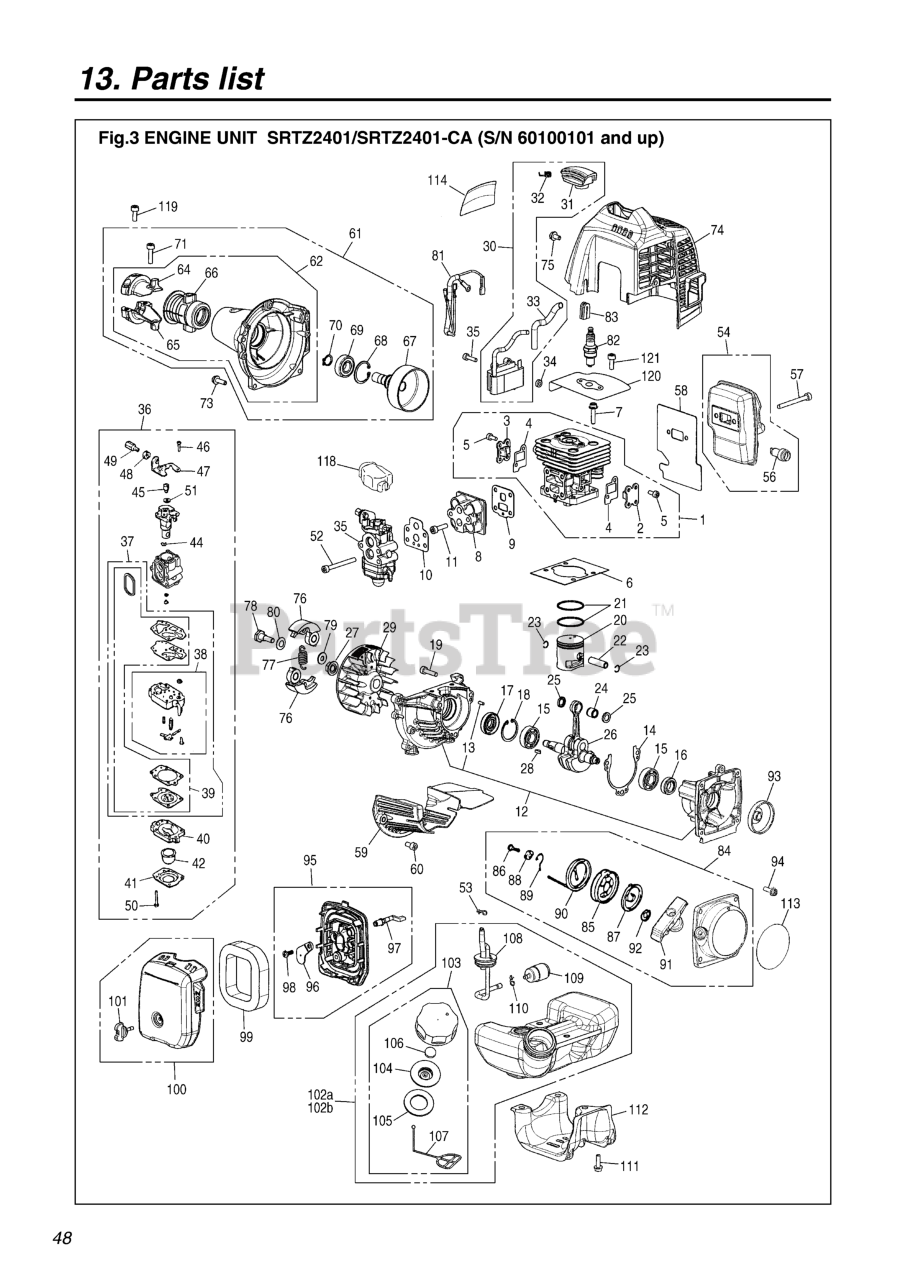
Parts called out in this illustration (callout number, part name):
1	CYLINDER COMP
2	COVER, TR-S
3	COVER, TR-F
4	GASKET, TR
5	BOLT
6	GASKET, BASE
7	BOLT TORX
8	INSULATOR
9	GASKET
10	GASKET
11	BOLT, TORX
12	CRANKCASE COMP
13	PIN
14	GASKET, CASE
15	BEARING
16	SEAL
17	SEAL
18	RING
19	BOLT TORX
20	PISTON
21	RING
22	PIN
23	RING
24	BEARING
25	WASHER
26	CRANKSHAFT COMP
27	NUT
28	KEY
29	ROTOR
30	COIL ASSY
31	CAP
32	SPRING
33	TUBE
34	SPACER
35	BOLT TORX
36	CARBURETOR ASSY
37	REBUILD KIT
38	BODY ASSY
39	GASKET KIT
40	BODY
41	COVER
42	PUMP
44	RING
45	SWIVEL
46	SCREW
48	NUT
49	SCREW
50	SCREW
51	WASHER
52	BOLT TORX
53	CLIP
54	MUFFLER ASSY
56	ARRESTER
57	BOLT TORX
58	GASKET, MUFF
59	PLATE
60	BOLT TORX
61	HOUSING ASSY
62	HOUSING COMP
64	BRACKET (A)
65	BRACKET (B)
66	CUSHION
67	DRUM
68	RING
69	BEARING
70	SNAP RING
71	BOLT TORX
73	BOLT TORX
74	COVER, ENGINE
75	BOLT TORX
76	SHOE
77	SPRING
78	SCREW
79	WASHER
80	WASHER
81	CORD COMP.
82	SPARK PLUG
83	GROMMET
84	RECOIL ASSY
85	REEL
86	SCREW
87	SPRING
88	COLLAR
89	ARM
90	ROPE
91	KNOB
92	PLATE
93	PULLEY
94	BOLT, TORX
95	BODY ASSY
96	PLATE, CHOKE
97	LEVER
98	SCREW
99	ELEMENT
100	COVER ASSY
101	KNOB
102B	TANK ASSY
103	CAP ASSY
104	HOLDER ASSY
105	PACKING
106	FILTER
107	STOPPER
108	PIPE COMP
109	FILTER ASSY
110	CLIP
111	BOLT TORX
112	GUARD, TANK
113	LABEL, RECOIL
114	LABEL, COVER
118	COVER
119	BOLT TORX
120	PLATE
121	BOLT TORX
